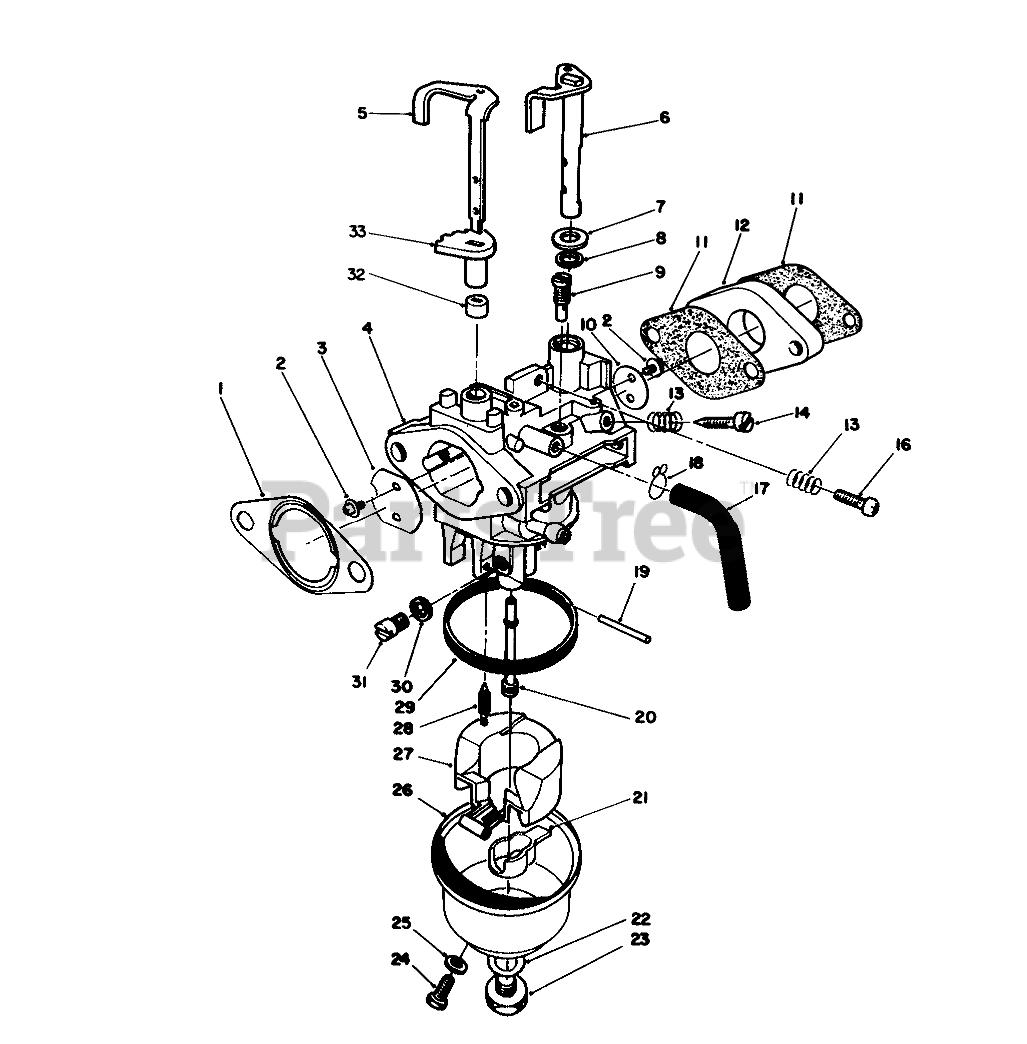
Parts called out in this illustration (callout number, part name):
1	GASKET F/W ENGINE
2	Screw
3	VALVE
4	Body-Carburetor
5	Shaft-Choke Valve
6	SHAFT
7	WASHER
8	Seal-Throttle Shaft
9	JET - PILOT
10	VALVE
11	GASKET INTAKE
12	INSULATOR - CARB.
13	SPRING-PILOT SCREW
14	ADJUSTER
16	SCREW
18	CLAMP
19	Pin
20	NOZZLE - MAIN
21	SPACER
22	GASKET
23	SCREW
24	SCREW
25	GASKET
27	FLOAT
28	NEEDLE
29	FLOAT BOWL GASKET
30	SPACER
31	JET - MAIN
32	LOWER CHOKE RING
33	UPPER CHOKE RING
